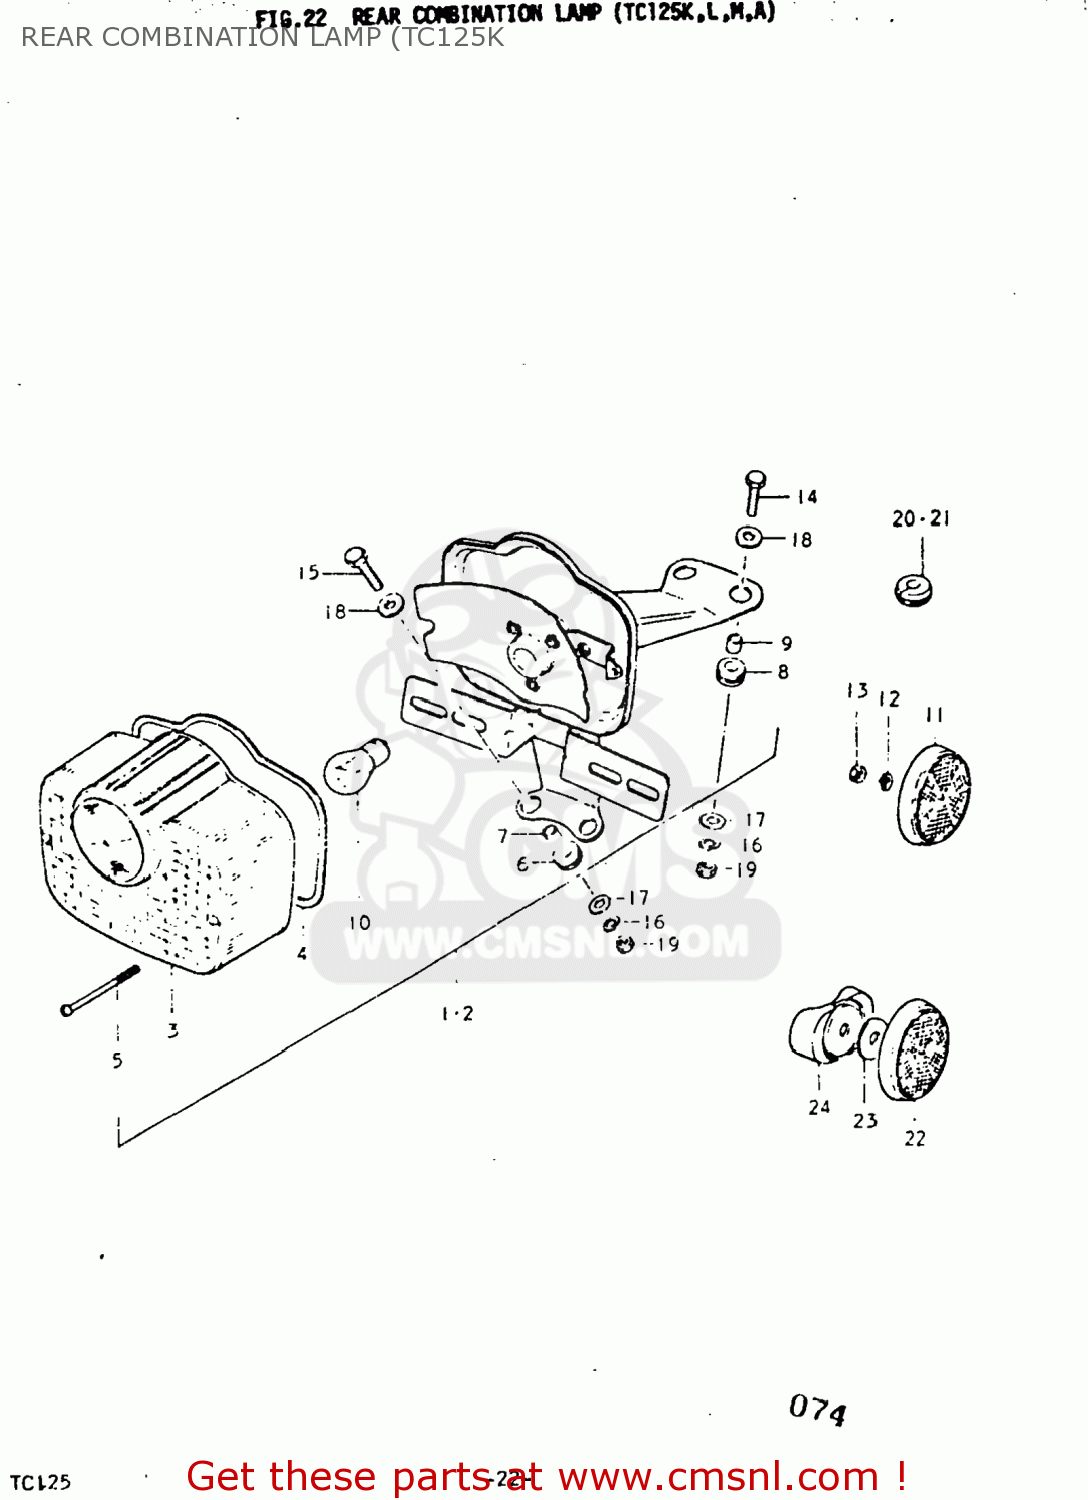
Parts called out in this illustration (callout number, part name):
1	LAMP ASSEMBLY,REAR COMBINATION
2	LAMP ASSEMBLY,REAR COMBINATION
3	LENS,REAR COMBINATION LAMP
4	LENS,REAR COMBINATION LAMP
5	SCREW
6	CUSHION
7	SPACER,REAR COMBINATION LAMP
8	CUSHION
9	SPACER,REAR COMBINATION LAMP
10	BULB(6V32/3CP,STANLEY)
11	REFLECTOR,REFLEX
12	LOCK WASHER
13	NUT
14	BOLT
15	BOLT
16	LOCK WASHER
17	WASHER
18	WASHER
19	NUT
20	GROMMET
21	GROMMET
22	REFLEX REFLECTOR ASSEMBLY
23	WASHER
24	SPACER
